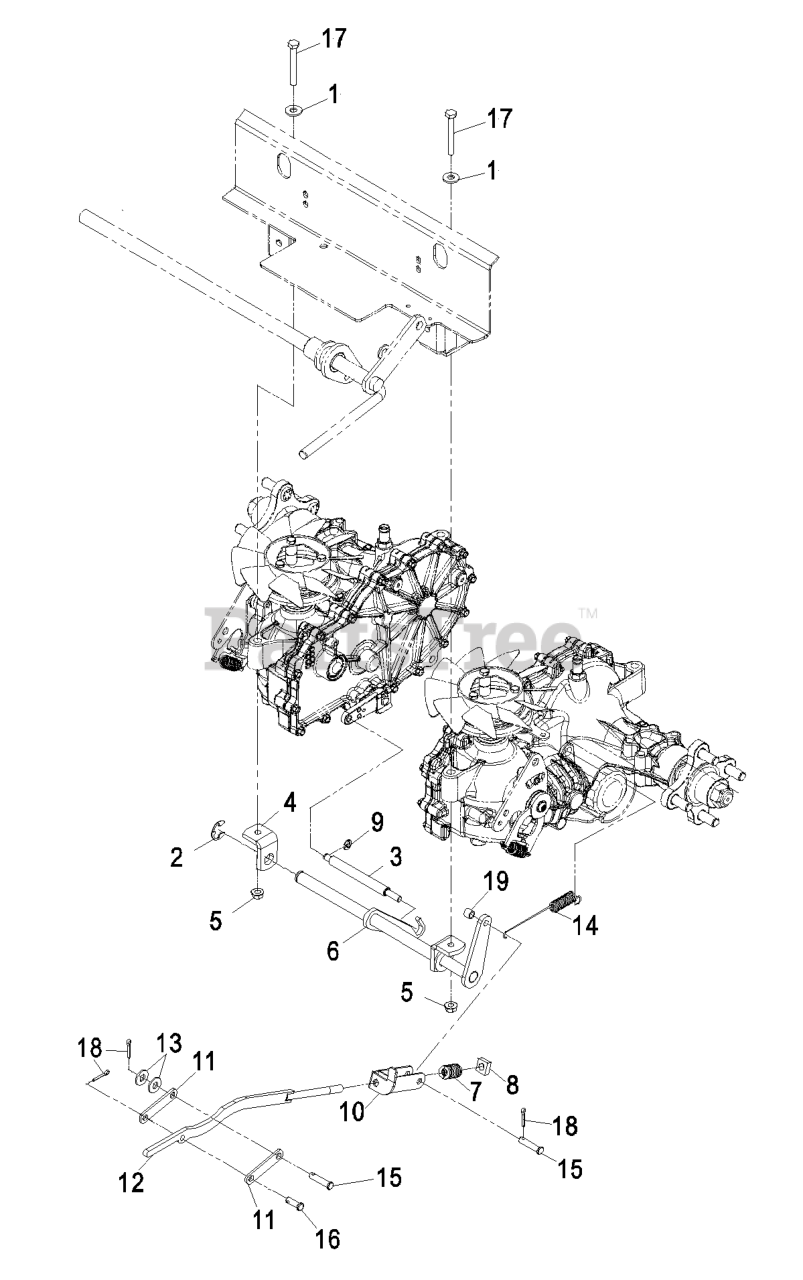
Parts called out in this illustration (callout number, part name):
1	WASHER-FLAT
3	BAR-EQUALIZER
4	BRACKET-PIVOT, BRAKE
5	NUT-HF, NI
6	BELLCRANK-BRAKE
7	SPRING-BRAKE
8	NUT-SQUARE
9	RING-RETAINING, EXT
10	CLEVIS-BRAKE
11	LINK-CENTER, OVER
12	LINK-BRAKE
13	WASHER-PLAIN
14	SPRING-RETURN, BRAKE
15	PIN-CLEVIS
16	PIN-CLEVIS
17	SCREW-HH
18	PIN-COTTER
